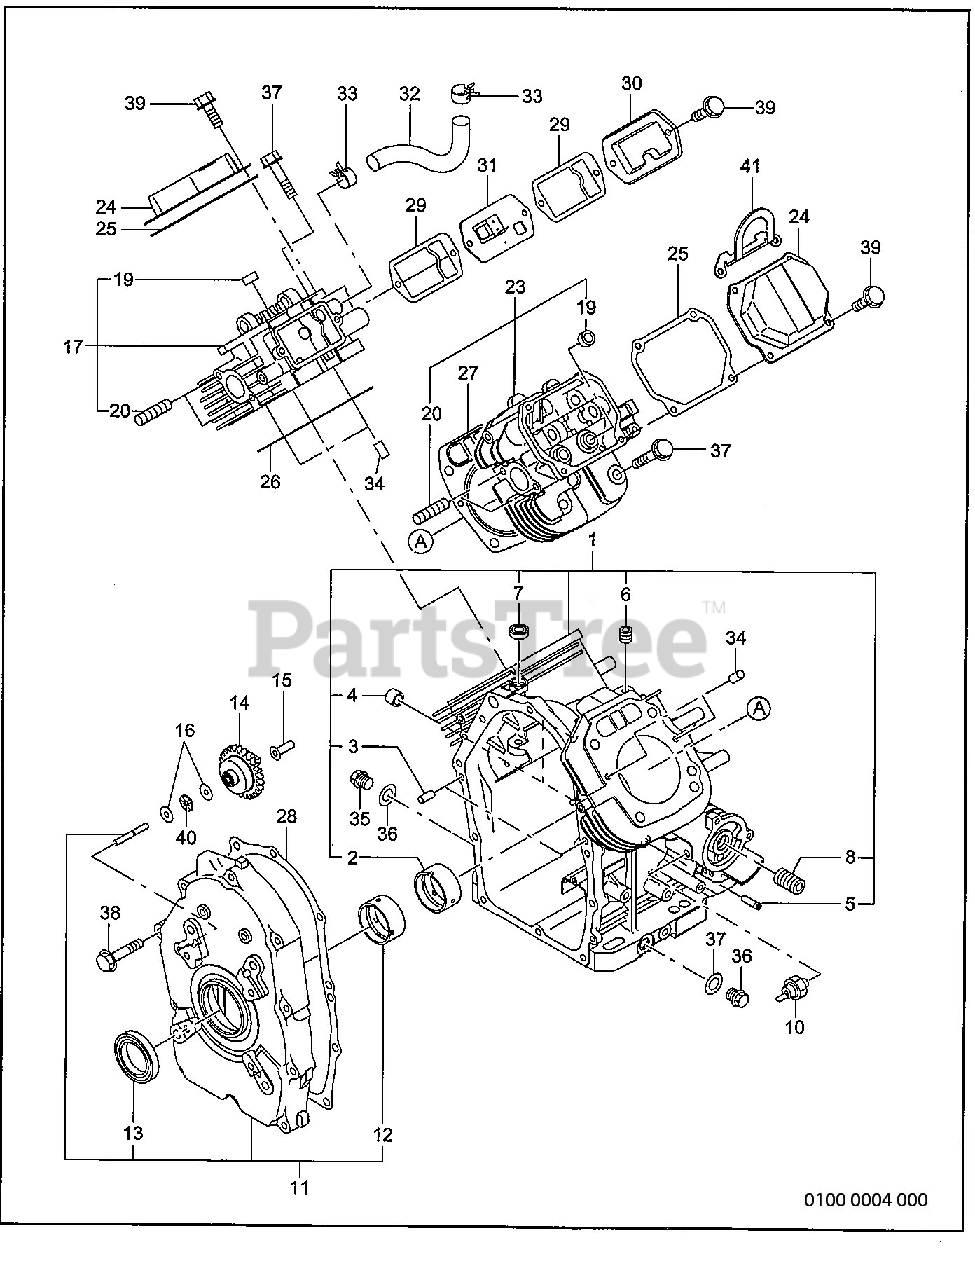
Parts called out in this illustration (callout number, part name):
1	CRANKCASE ASSY
10	SWITCH OIL PRESSURE
11	MAIN BEARING COVER ASSY
14	GOVERNOR GEAR ASSY
15	GOVERNOR SLEEVE
17	CYLINDER HEAD 1 ASSY
19	SEAL-INTAKE VALVE
23	CYLINDER HEAD 2 ASSY
24	ROCKER COVER ASSY
25	GASKET, rocker cover
26	GASKET 1, cyl. head
27	GASKET 2, cyl. head
28	GASKET, main bearing cover
29	GASKET, breather plate
30	BREATHER COVER
31	BREATHER PLATE ASSY
37	FLANGE BOLT
38	FLANGE BOLT
39	FLANGE BOLT
40	THRUST BEARING
